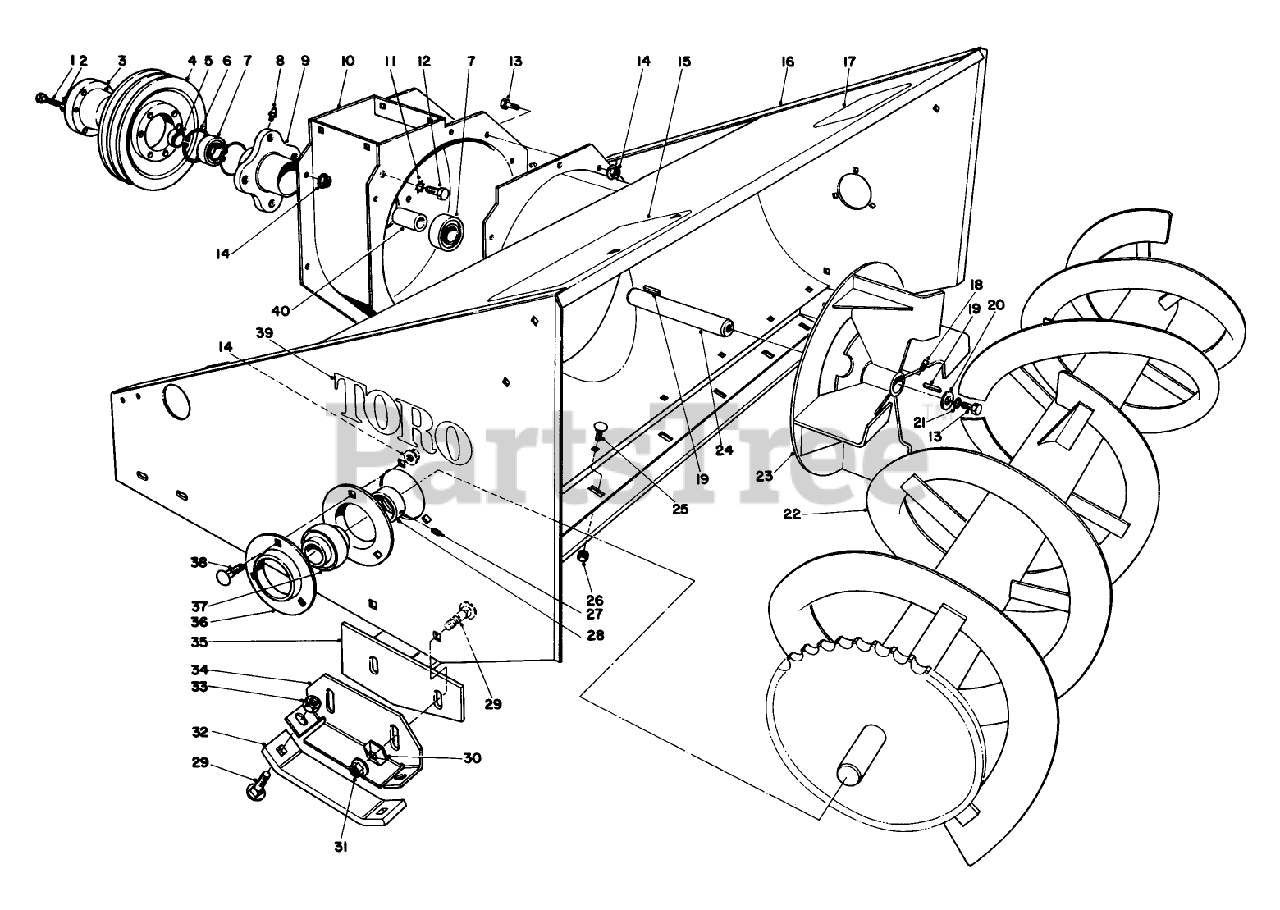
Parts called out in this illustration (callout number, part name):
1	SCREW-HH
2	WASHER-LOCK
3	Hub-"QD" (Incl. Ref. #1 & 2)
4	Pulley-"QD"
5	SPACER
6	RETAINING RING
7	BEARING
8	FITTING-LUBE, 45 DEG
9	SPINDLE HOUSING
10	BLOWER HSG WA
11	WASHER-LOCK, EXT
12	SCREW-HH
13	SCREW-HH
14	NUT-HF
15	Decal-Rear Weight
16	Auger Housing
17	Decal-Warning
18	SCREW-SET
19	Square Key
20	WASHER
21	WASHER-LOCK
22	Auger
23	IMPELLER WA 60096
24	IMPELLER SHAFT
25	SCREW-CARR
26	NUT-LOCK, NI
27	SCREW-SET, HSH
28	COLLAR-LOCK, BEARING
29	BOLT-CARR
30	LOCKWASHER-PYRAMID
31	FLANGE NUT W/LG FLG
32	SKID SHOE R
33	NUT-LOCK, CONE
34	SKID MTG PLT
35	SCRAPER WA
36	FLANGE
37	Bearing (Incl. Ref. #27 & 28)
38	SCREW-CARR
39	DECAL
40	SLEEVE 16107
